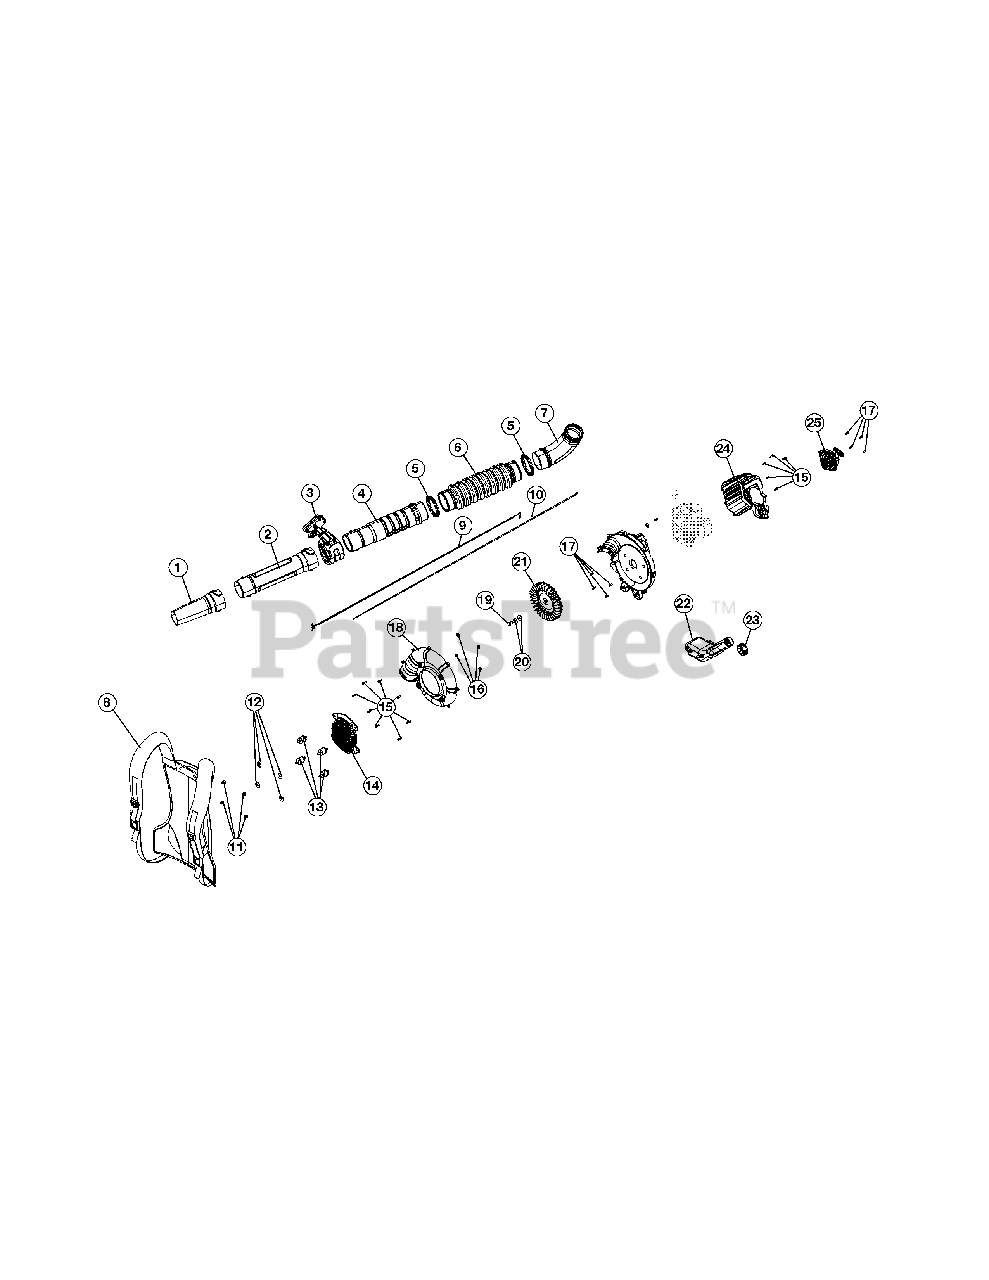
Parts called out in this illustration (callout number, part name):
2	Lower Blower Tube
3	Throttle Grip Assembly
4	Upper Blower Tube
10	Throttle Cable
11	Nut
12	Washer
13	Insulator Mount
14	Intake Cover
17	Screw
18	Impeller Housing Assembly (Incl Ref No. 13-17)
20	Impeller Hardware (Incl Ref No. 19)
21	Impeller (Incl Ref No. 19 & 20)
22	Fuel Tank Assembly (Incl Ref No. 23)
24	Housing Assembly (Incl Ref No. 15)
25	Starter Assembly (Incl Ref No. 17)
